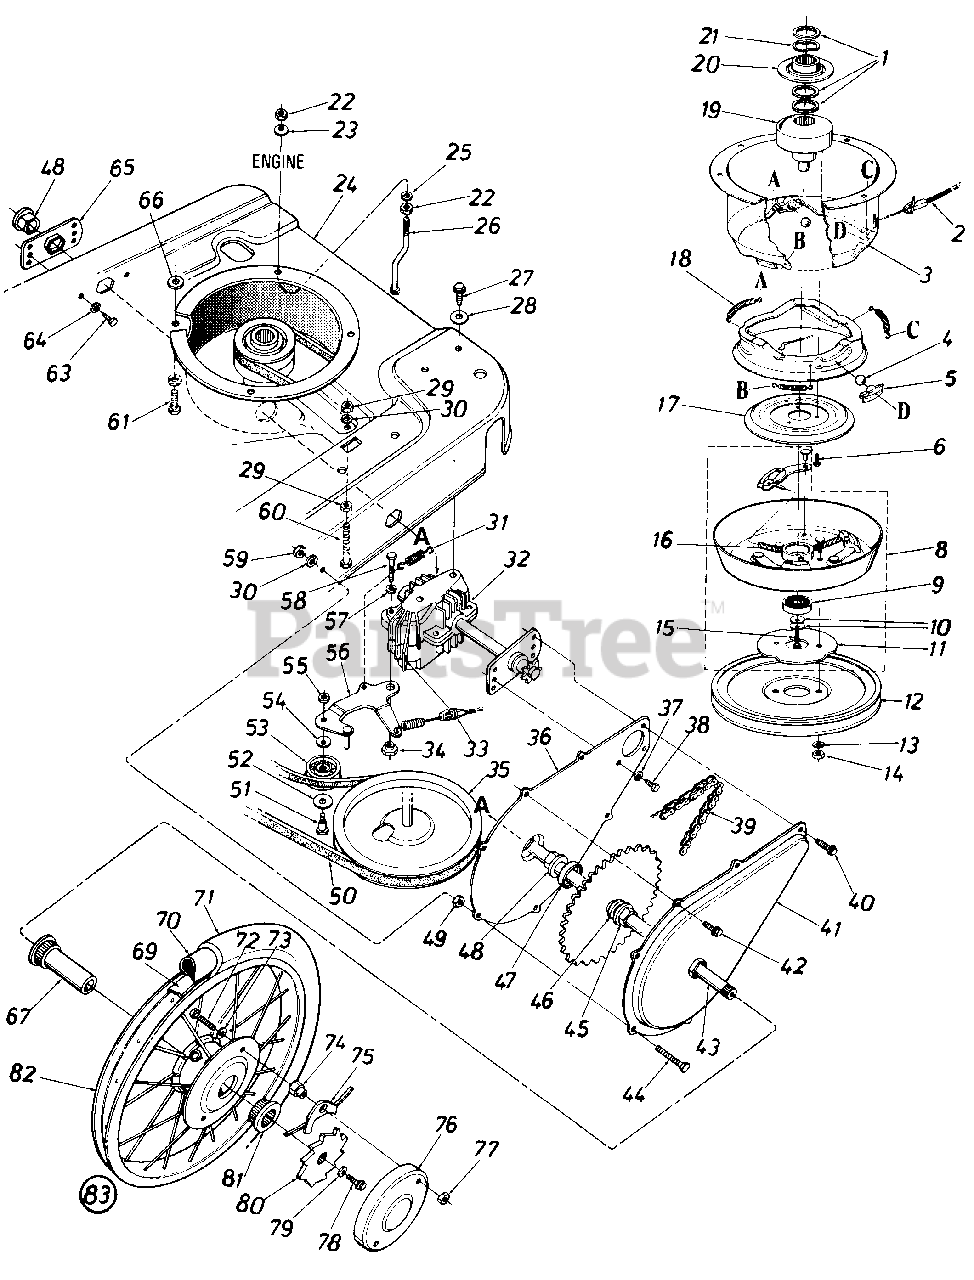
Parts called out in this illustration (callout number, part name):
1	Washer 1.00" I.D. x 1.20" O.D.
2	BBC Clutch Cable 46" Lg. 0 Black
3	Clutch Housing
4	Steel Ball .500" Dia.
6	Hex Wash. TT-Tap Cl. Scr. 1/4-20 x .75" Lg.
8	Clutch Blade Housing Ass'y.
9	Ball Brg. 669" I.D. x 1.574" O.D
10	Bell-Wash. .400" I.D. x .88" O.D.
11	Blade Disc.
12	5/8 "V"-Pulley 1.58" I.D. x 8.0" O.D.
13	L-Wash. 3/8" I.D.
14	Hex Nut 3/8-24 Thd.*
15	Hex Cent. L-Bolt 3/8-24 x 2.00" Lg.
16	Comp. Spring .33" O.D. x 2.05" Lg.
17	Brake Cup Cone
18	Extension Spring .35" O.D. x 1.80" Lg.
19	Fixed Pulley MBC Adapter
20	Movable Pulley Half
21	Wave Wash. .164 High x 1.005" I.D.
22	Hex Nut 5/16-18 Thd.*
23	Bell-Wash. .336" I.D. x .860" O.D.
24	Hi-Wheel Frame
25	L-Wash. 5/16" I.D.*
26	Belt Guard 5/16" Bolt
27	Hex Wash. Hd. B-Tap Scr. 5/16-18 x .50" Lg.
28	Bell-Wash. .378" I.D. x 1.110" O.D.
29	Hex Nut 1/4-20 Thd.
30	L-Wash. 1/4" I.D.*
31	Extension Spring .33" I.D. x 1.12" Lg.
32	See Transmission Breakdown
33	Self-Propelled Cable x 50" Lg. Black
34	Shld. Spacer .375" Dia. x .170
35	Fl-Pulley 5.06" O.D.
36	45 Tooth Chain Cover
37	L-Wash. 1/4" I.D.*
38	Hex B-Tap Scr. 1/4 x .38" Lg.
39	#48 Chain .500" Pitch x 52 0 Links
40	Hex Wash. TT-Tap Scr. 1/4-20 x .50" Lg.
41	45 Tooth Chain Case
42	Hex B-Tap Scr. 1/4 X .38" Lg.
43	Rear Axle Ass'y. 26.82" Lg.
44	Hex Bolt 1/4-28 x .88" Lg.
45	Hex Flange Brg. .631" I.D. x .320
46	Fl-Wash. .635" I.D. x 1.0" O.D.
47	Spacer .630" I.D. x '.250" O.D.
48	Hex Flange Brg. .631" I.D. x .720
49	Hex Jam Nut 1/4-28 Thd.
50	"V"-Belt
51	Shld. Bolt .375" Dia. x 400 Lg.
52	Fl-Wash. .390" I.D. x 1.00" O.D.
53	Needle Brg. .375" x .31"
54	Bell-Wash. .265" I.D. x .75" O.D.
55	Hex Patch L-Nut 1/4-20 Thd.
56	Idler Brk't. Ass'y.
58	Hex Bolt 1/4-20 X 1.25" Lg.
59	Hex Nut 1/4-28 Thd.
60	Hex Bolt 1/4-20 X 2.00" Lg.*
61	Hex Wash. Hd. TT-Tap Scr. 3/8-16 x 1.0" Lg.
63	Hex B-Tap Scr. 1/4 X .38" Lg.
64	L-Wash. 1/4" I.D.
65	Hex Bearing Cup
66	Fl-Wash. .406" I.D. x .734" O.D.
67	Flange Bearing .630" I.D. x 2.83" Lg.
69	Rimstrip 16 x 7/8
70	Inner Tube 16 x 2.12
71	Chevron Tire 16 x 2.125
72	Hex Bolt Special 5/16-18 x 1.0" Lg.
73	Intern. L-Wash. 5/16" I.D.
74	Special Hex Nut 5/16-18 Thd.
75	Pawl and Spring Ass'y.
76	Wheel Cover 4.75" I.D.
77	Hex Nut 5/16-18 Thd.*
78	Hex Wash. Hd. Self-Tap Screw 1/4" X 3/4" Lg.
79	Bell-Wash. .265" I.D. x .75" O.D.
80	Wheel Ratchet 2.92" O.D.
81	Flange Bearing 1.004" I.D.
82	Rim Ass'y. Only 16.0" x 2.1
83	Wheel Ass'y. Comp. 16 x 2.12
